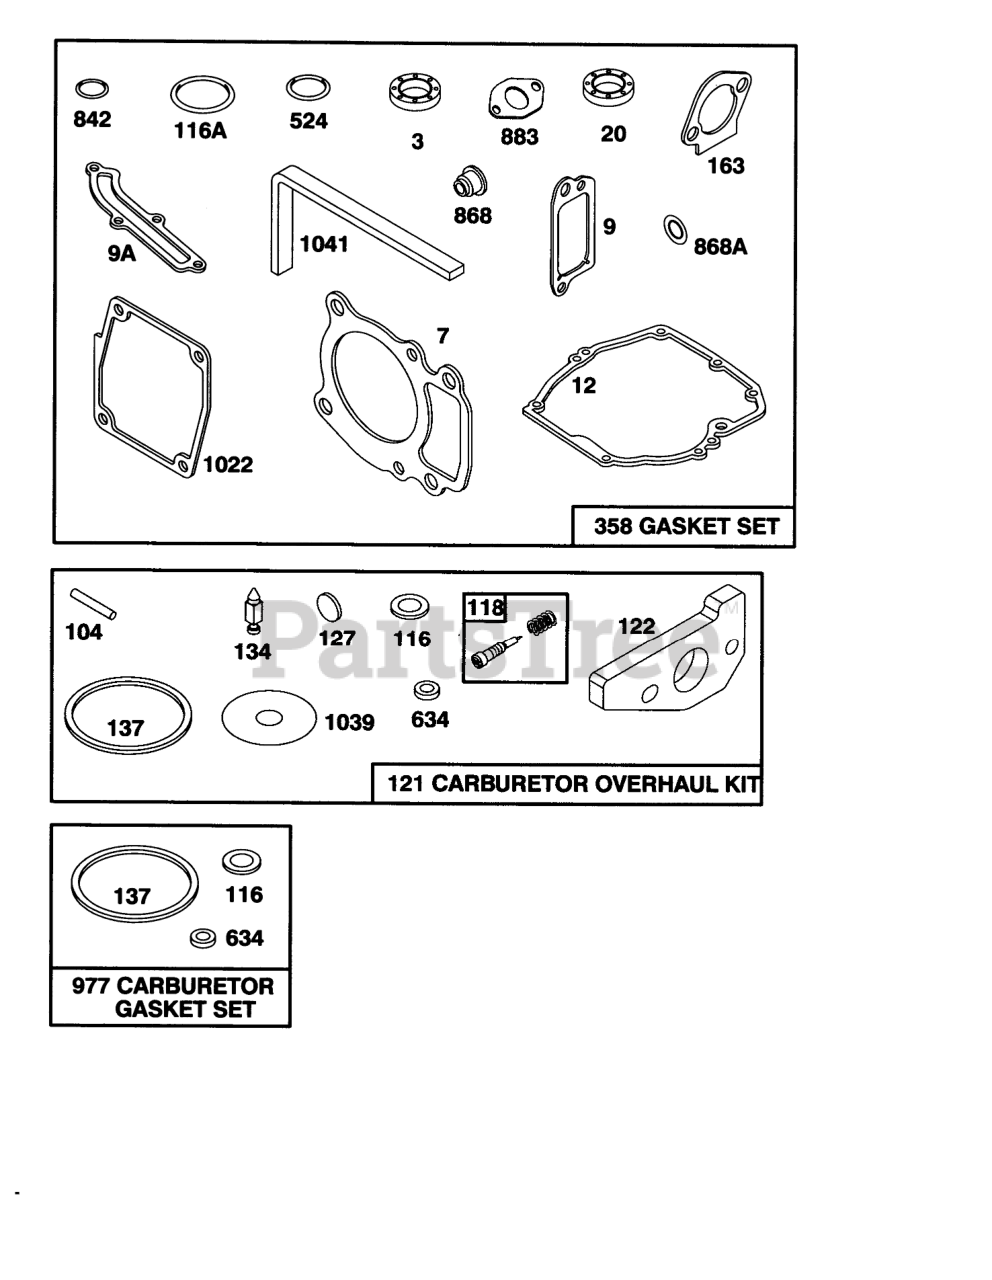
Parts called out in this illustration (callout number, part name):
3	SEAL - OIL
7	CYLINDER HEAD GASKET
9	BREATHER GASKET
9A	GASKET-BREATHER
12	ENGINE BASE GASKET
20	SEAL-OIL
104	FLOAT HINGE PIN
116	SEALING GASKET
116A	O RING SEAL
118	VALVE KIT - NEEDLE
121	CARBURATOR OVERHAUL KIT
122	ADAPTER ASSEMBLY
127	PLUG
134	Valve-Float (Includes Seat)
137	FLOAT BOWL GASKET
163	AIR CLEANER GASKET
358	GASKET SET
524	O-RING
634	SEAL WASHER
842	O-RING
868	SealAssy-Valve
868A	Seal-Valve
883	EXHAUST GASKET
977	CARBURATOR GASKET SET
1022	ROCKER COVER GASKET
1039	FLOAT LIMITER
1041	SEAL - FOAM
